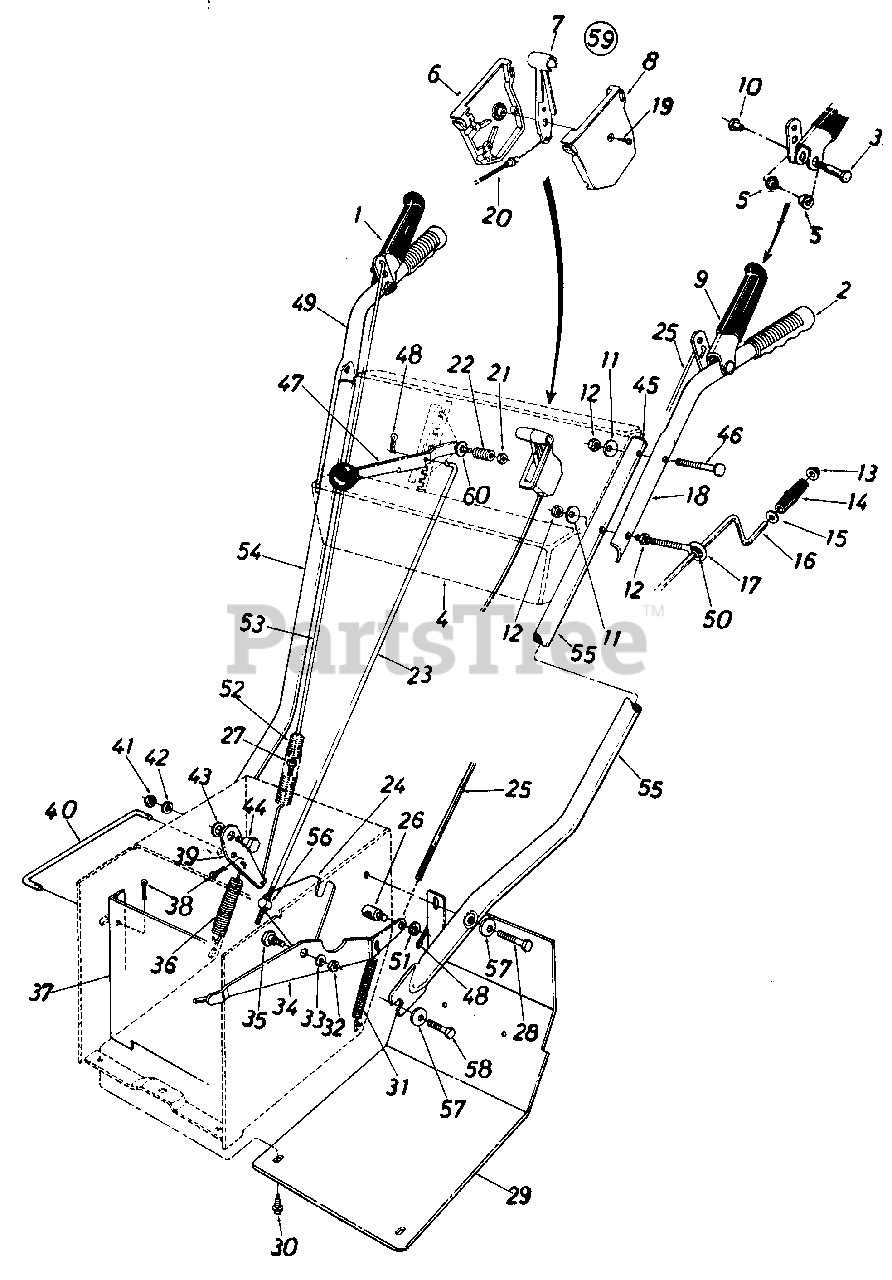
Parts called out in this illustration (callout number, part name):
1	Clutch Grip Ass'y.-R.H.
3	Shoulder Bolt .374 Dia. x 1.53" Lg.
4	Handle Panel Ass'y.
5	Hex Flange Plastic Bearing .380" I.D.
9	Clutch Grip Ass'y.-L.H.
10	Shoulder Nut 1/4-20 Thd.
11	Bell-Wash. .34" I.D. x .88" O.D.
12	Hex Nut 5/16-18 Thd.
13	Push Nut 3/8" Rod
14	Knob 3/8" Rod
15	Fl-Wash. .40" I.D. x .62" O.D.
16	Chute Crank Ass'y.
17	Eye Bolt 5/16-18 x 5.0" Lg.
18	Upper Handle-L.H.
20	Throttle Control Wire
21	Hex Ins. Jam L-Nut 3/8-24 Thd.
22	Compression Spring .50" O.D. x .88" Lg.
23	Shifting Rod 5/16" x 32.50" Lg.
24	5hifting Linkage Bracket
25	Lockout Rod .214" Dia. x 36.0" Lg.
26	Adjustment Ferrule 1/4-20
27	Hex Ins. L-Nut 1/4-20 Thd.
28	Hex BoIt 3/8-16 x 2.00" Lg.
29	Frame Cover
30	Hex Wash. Self-Tap Scr.1/4-20 x .50" Lg.
31	Extension Spring .38" O.D. x 3.25" Lg.
32	Hex Jam Nut 3/8-16 Thd.
33	L-Wash. 3/8" I.D.
34	Auger Clutch Bracket Ass'y.
35	Shld. Bolt .625" Dia. x .170
36	Extension Spring .75" O.D. x 4.31" Lg.
37	Drive Pulley Support Brkt. Ass'y.
38	Cotter Pin 3/32" Dia. x .75" Lg . *
39	Drive Clutch Bracket
40	Drive Clutch Rod
41	Hex Jam Nut 3/8-16 Thd.
42	L-Wash. 3/8" I.D.
43	Fl-Wash. .34" I.D. x .75" O.D
44	Shld. Bolt .625" Dia. x .170
45	Plastic Plug
46	Carriage Bolt 5/16-18 x 2.0" Lg.
47	Shift Handle Ass'y.
48	Int. Cotter Pin 5/16" Dia.
49	Upper Handle-R.H.
50	Grommet
51	Fl-Wash. .28" I.D. x .62" O.D
52	Extension Spring .75" O.D. 5.00" Lg.
53	Lockout Rod .214" Dia. x 32" Lg.
54	Lower Handle-R.H.
55	Lower Handle-L.H.
56	Adjustment Ferrule
57	Bell-Wash. .40" I.D. x .88" O.D.
58	Hex Wash. Self-Tap Scr. 3/8-16 x .75" Lg.
59	Throttle Control Box Ass'y.
60	Bell-Wash. .40" I.D. x .88" O.D.
